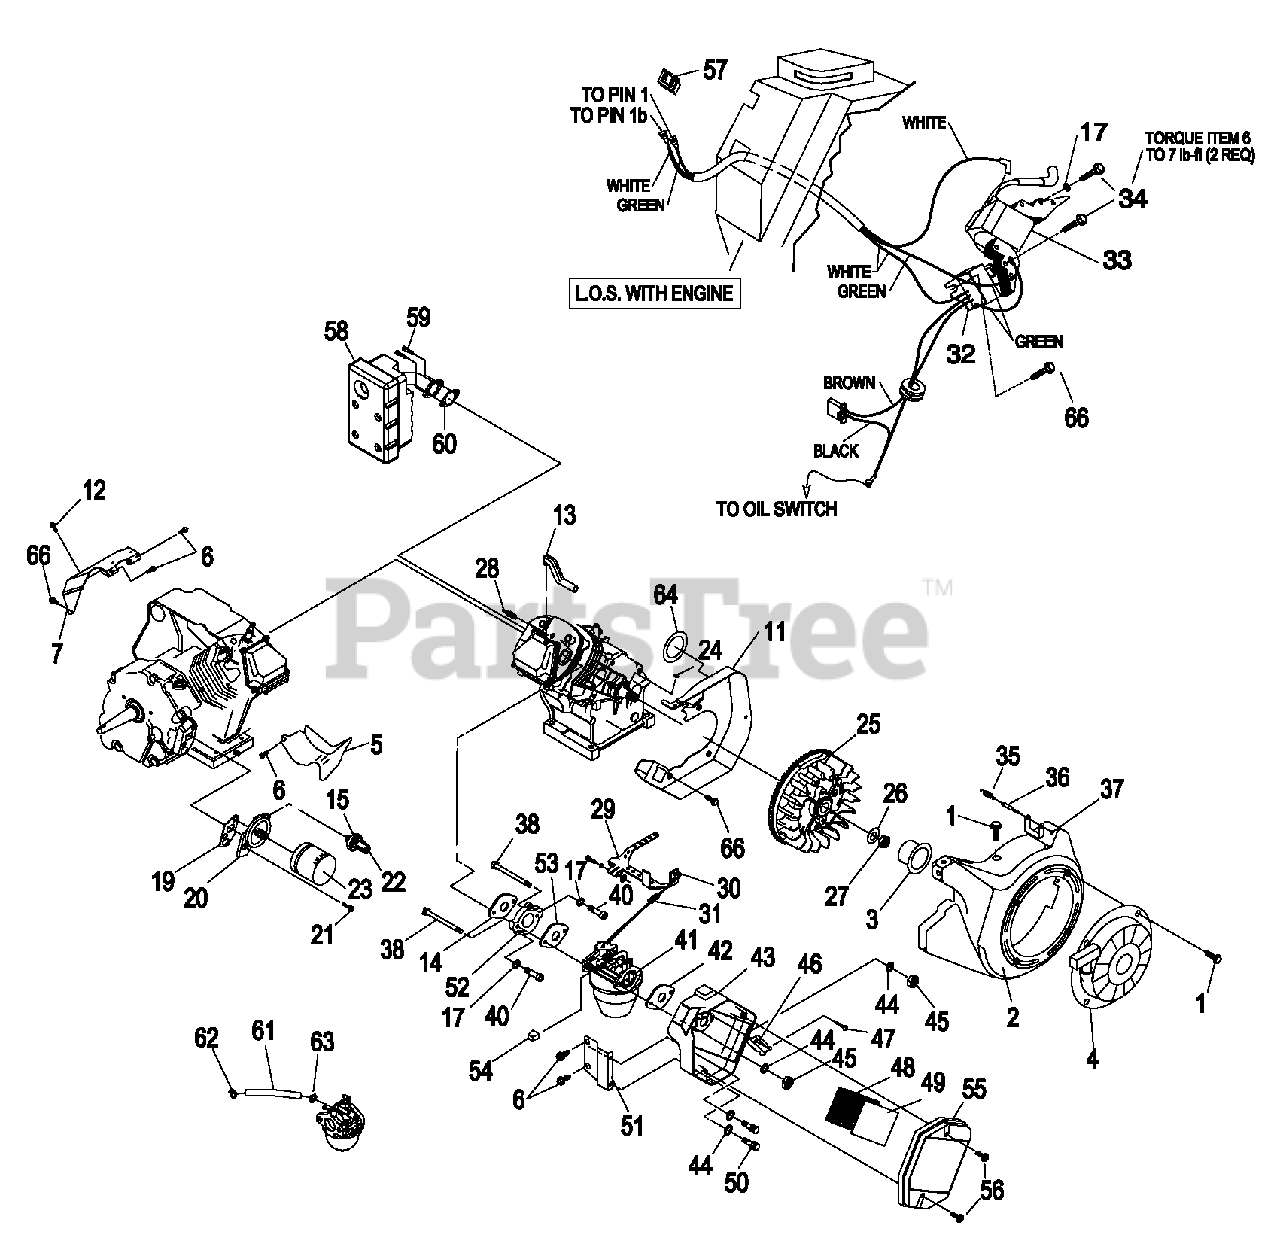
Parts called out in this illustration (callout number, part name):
1	SCREWHHTT M5-1.5X 8ZYC
2	ASSEMBLY, BLOWER HOUSING
3	PULLEY STARTER LARGEFRAME
4	REDOIL STARTER LARGE FRAME
5	WRAPPER, BOTTOM t2 HPHS
6	SCREW HHTT M5-1.5X10 YELLOWCHROME
7	WRAPPER, TOP REGULAR STEEL
11	BACKUPLATE W ELECTRIC START
12	SCREW, HHTT M8-1.25 X16 YELLOWCHROME
13	HOSE BREATHER? GH410 ENGINES
14	GASKET,INTAKE ADAPTER
15	SCREW PPH M#8-32X 1/4
17	WASHER LOCK MS- 1/4
19	GASKETOIL FILTER ADAPTER?
20	ADAPTER,OIL FILTER NO TAPPED HOLES
21	SCREW, SHC M8-1.25 X30 G129
22	SWITCH, HD EES OIL PRESSURES PSI
23	FILTER OIL75 MM NO LOGO
24	KeY, WOOD RFF4X 19D
25	FLYWHEEL, WITH RING GEAR 27 DEGREE
26	WASHER, BELV-20X22
27	NUT HEX M20-15 G8 YLWCHROME FLYWHEEL
28	SPARKPWG, CHAMPION RC14VC
29	ASSEMBLY, GOVERNOR LEVER t12HP
30	ROD, GOVERNOR CONTROL
31	SPRING, ANTHLASH
32	ASSEMBLY, LOS MODULE
33	ASSEMBLY, IGNITION ADV NO D D DEG H 410
34	SCREW HHPC M6-1.0 X 25
35	SPRING GOVERNOR 320/360/410
36	BOLT, GOVERNOR ADJ USTMENT M5
37	NUT, HEX LOCK M5-O.8 NYION INSERT ZINC
38	BOLT,CARBURETOR MOUNTING
40	SCREW, SHC M6- 1.0X20 G129 ZINC PLATED
41	CAR BURETOR, 41OHS
42	GASKET, AIR CLEANER?
43	BASE, AIRCLEANER 410 HI FLOW
44	WASHER FIAT M5
45	NUT, HEX LOCK M5-1.0 NYLON INSERT
46	PLATE, SPIT BACK
47	SCRRV. PLASTTTE #8 X 37 LONG
48	ELEMNT, AIR FILTER
50	SCREW, HHC M6-1.0X 16 WW LOCK WASHER
51	BRACKET, AIR CLEANER
52	ADAPTER, "K"
53	GASKET, CARBURETOR/MANFOLD
54	KNOB, CHOKE LEVER
55	COVER, AIR CLEANER 13GN
56	BOLT, AIR CLEANER COVER
57	SWITCH, ENGINE RUN-STOP
58	MUFFLER, 410 SIDEOUT ALUMINZED
59	SCREW, SHC M6-1.25 X20 G129
60	GASKET, EXHAUST
61	H0SE, 1/4" SA E0R7 SETIFLEX6"
62	CLAMP, HOSE BAND1/2"
63	CLAMP, HOSE WORM GEAR
64	PLUG PLASTIC 1.875
66	SCREW HHFC M6-1.0X12
